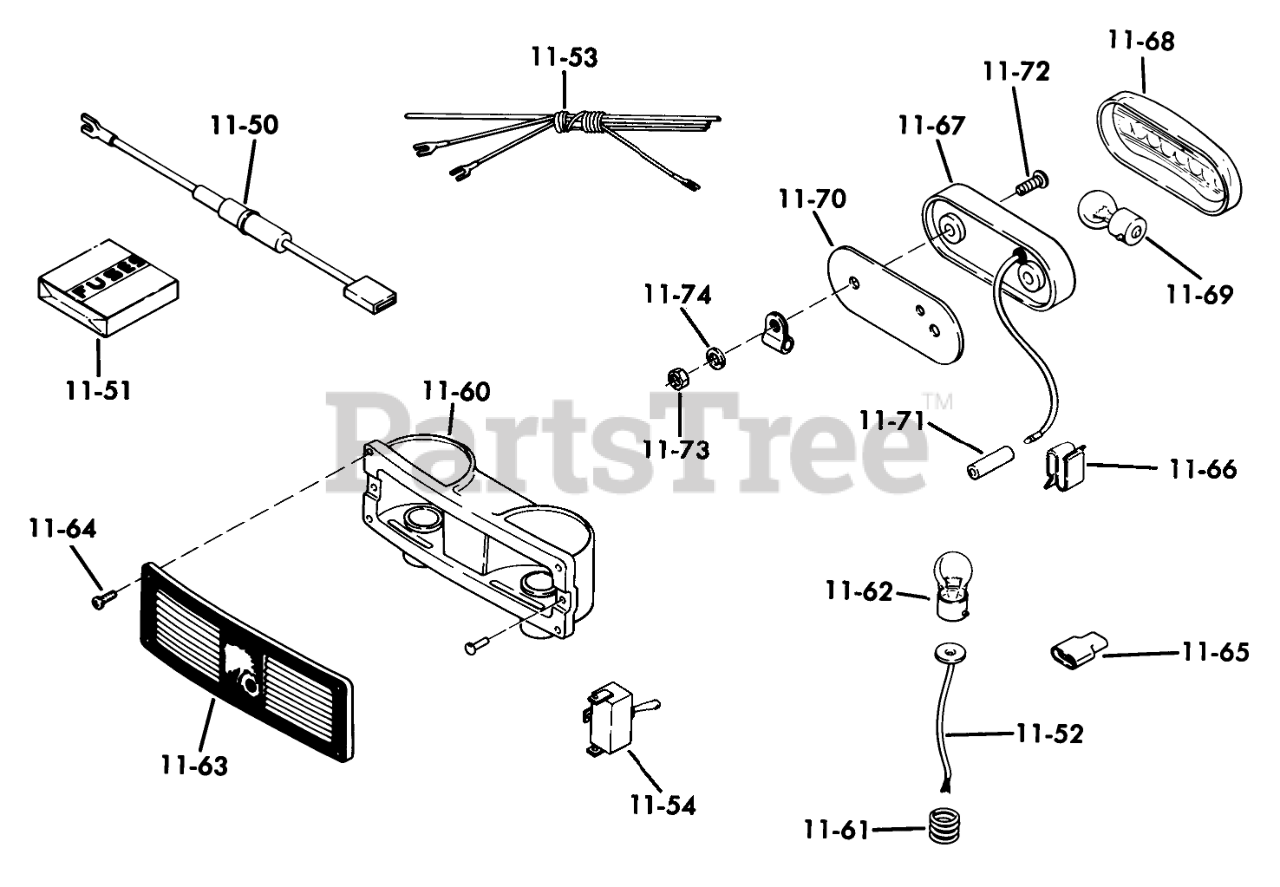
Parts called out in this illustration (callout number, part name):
11-50	ASSY FUSED CONNECTOR
11-52	WIRE ASSY
11-53	Wire Harness-Lights
11-54	SWITCH-LIGHTS
11-60	ASSY REFLECTOR HOUSI
11-61	SPRING
11-62	BULB
11-63	Lens
11-64	Pan HD Swage
11-65	CONNECTOR 3 WIRE
11-66	SPEED CLIP
11-67	Base
11-68	Lens
11-69	Bulb
11-70	Mounting Pad
11-71	CONNECTOR 2 WIRE
11-72	Screw
11-73	Nut
11-74	Lockwasher
